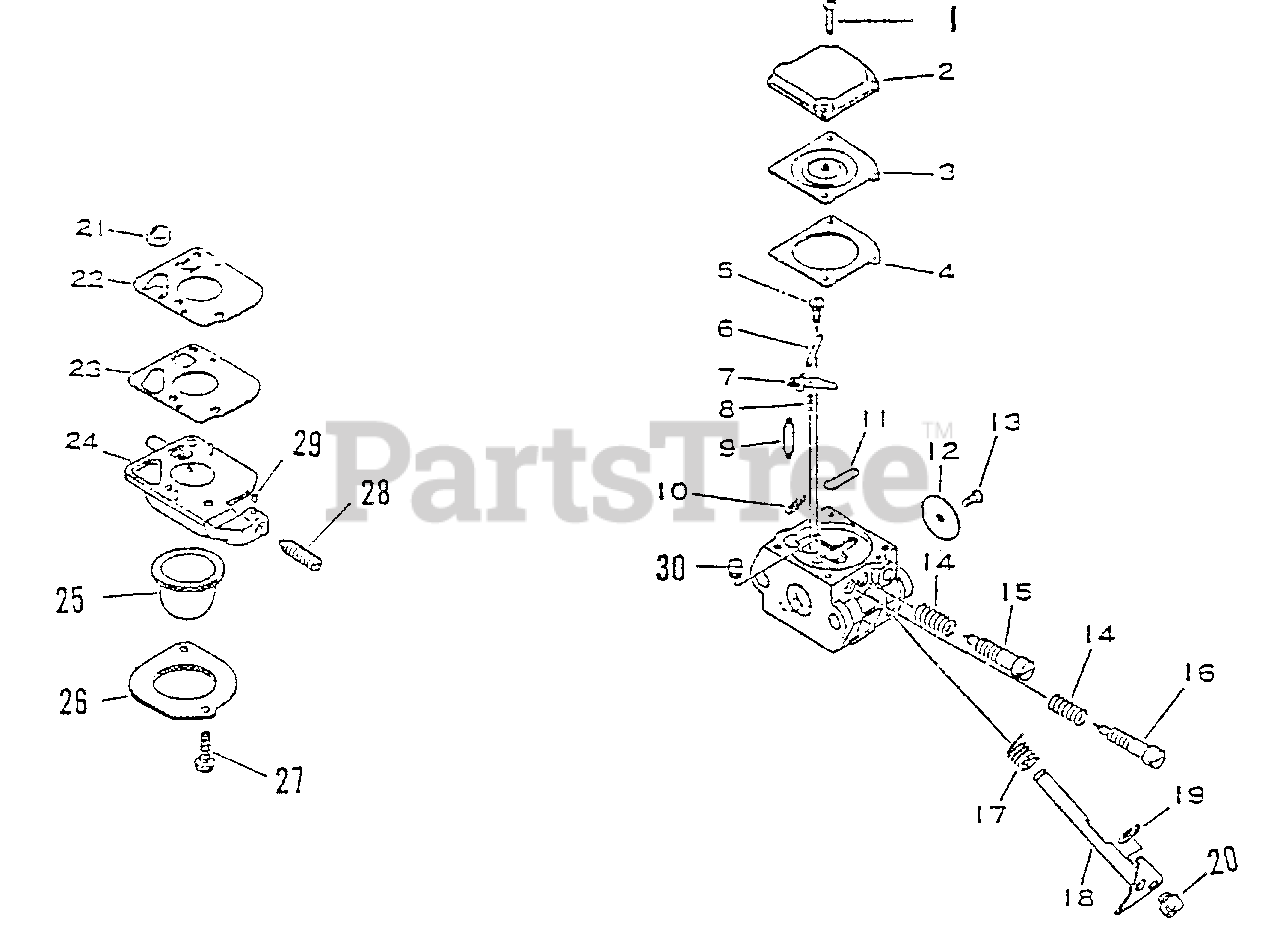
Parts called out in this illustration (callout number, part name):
2	COVER, METERING
3	DIAPHRAGM
4	GASKET, DIAPHRAGM
5	SCREW
6	PIN, METERING LEVER
7	LEVER, METERING
8	SPRING
9	VALVE, NEEDLE
10	RING, RETAINING
11	PLUG, WELCH
12	VALVE, THROTTLE
15	NEEDLE - HIGH SPEED
16	NEEDLE - LOW SPEED
17	SPRING, RETURN
18	SHAFT, THROTTLE
19	RING, RETAINING
21	STRAINER
22	DIAPHRAGM, PUMP
23	GASKET, PUMP
24	COVER, PUMP
25	BULB, PURGE
26	RETAINER, PURGE BULB
27	SCREW, RETAINER
28	SCREW, IDLE ADJUST
29	PIECE, FRICTION
30	NOZZLE, CHECK VALVE
